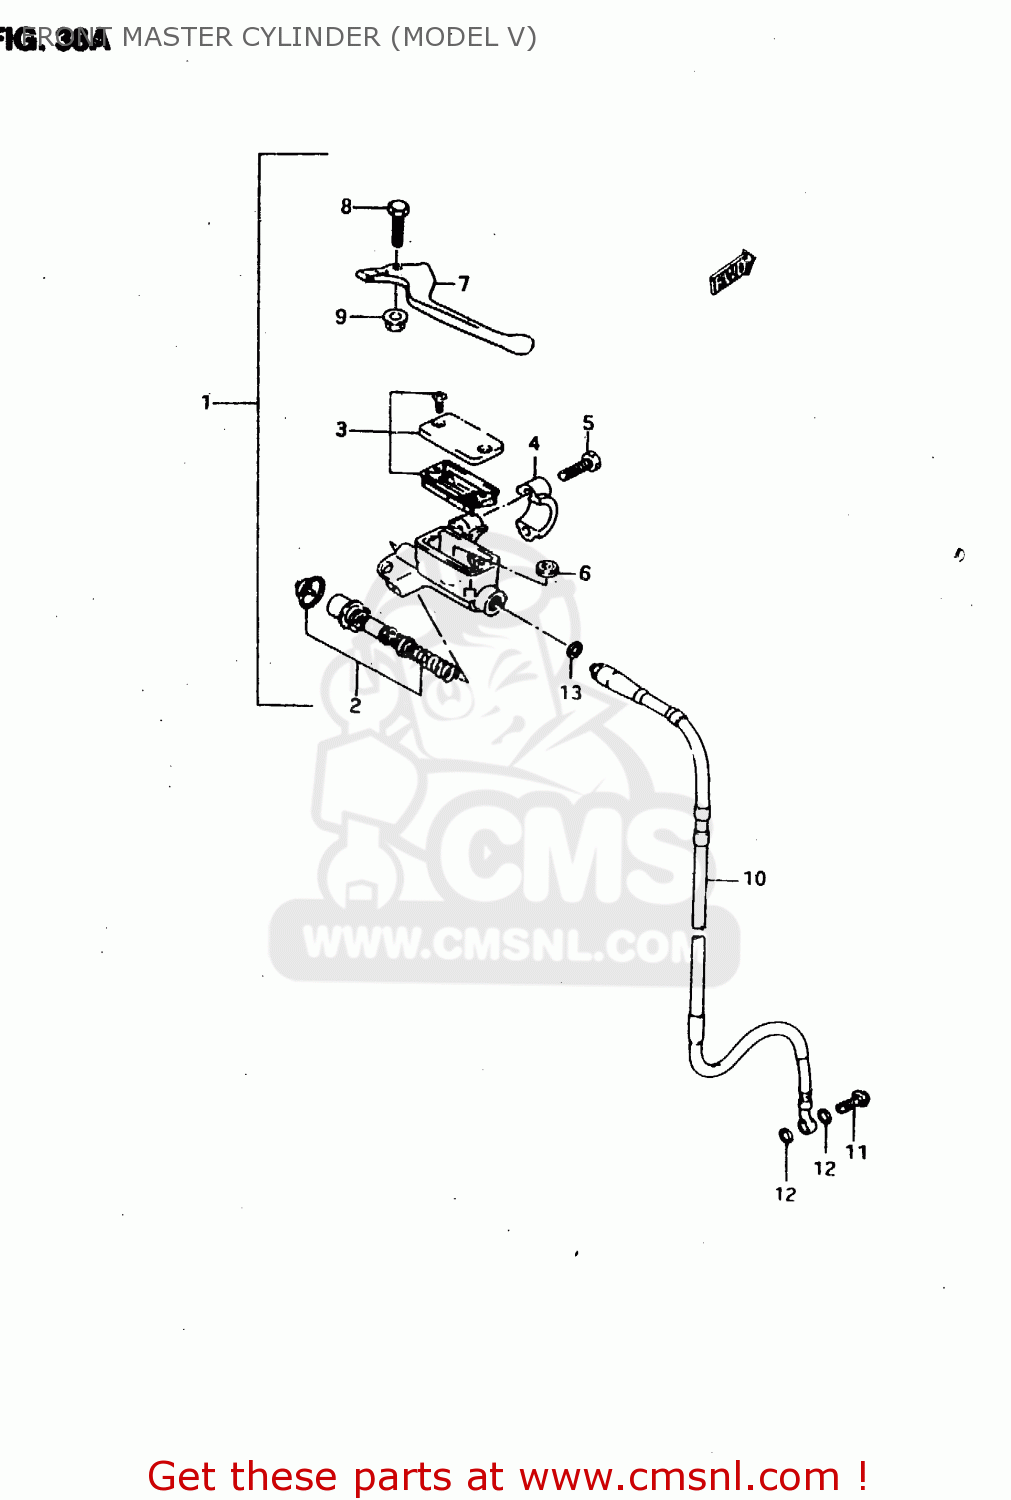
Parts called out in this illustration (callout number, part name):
1	CYLINDER ASSY
2	PISTON&CUP SET
3	CAP SET
4	HOLDER
5	BOLT
6	PROTECTOR
7	BRAKE LEVER
8	BOLT
9	NUT
10	HOSE, FRONT BRAKE
11	BOLT
12	WASHER
13	WASHER
